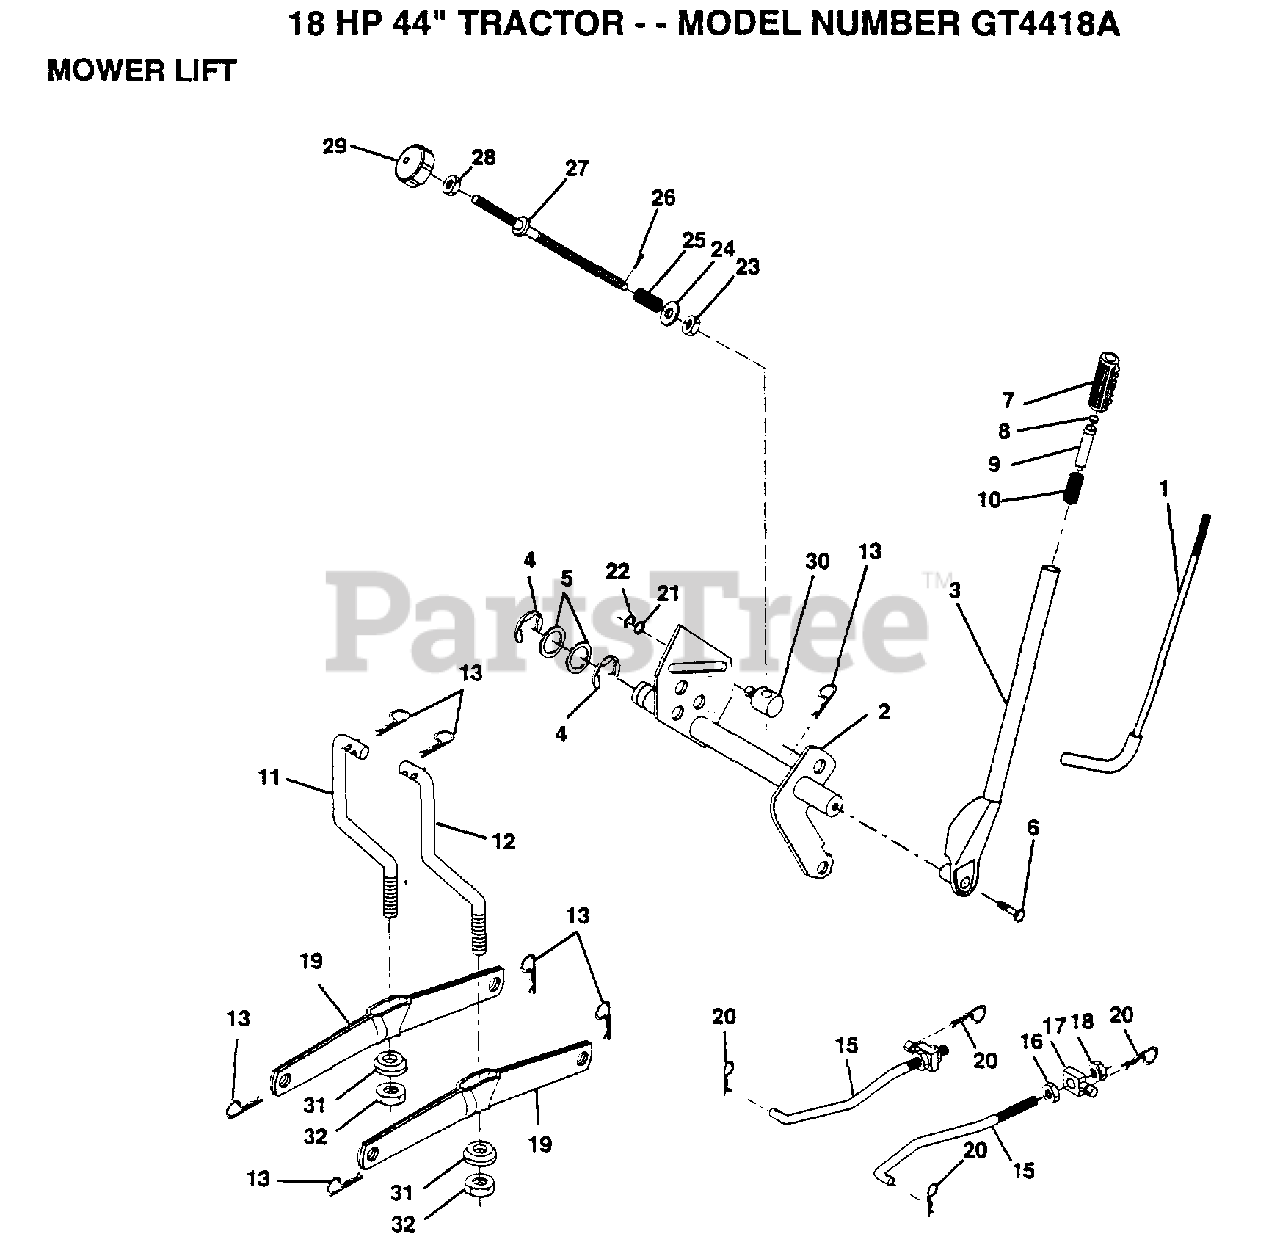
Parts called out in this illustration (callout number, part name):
1	LEVER ROD LT
2	SHAFT LIFT W/IND
4	E-RING
5	WASHER
6	"BOLT,HEX"
7	GRIP
10	SPRING T
11	LINK LIFT LH
12	LINK LIFT RH
15	LINK.FRONT
16	NUT
17	TRUNION
18	NUT.LK.W/WSH.1/2.
19	ARM SUSP REAR
20	RETAINER.SPRING
21	WASHER
22	KLIP RING
23	NUT T
24	WASHER
25	SPRING T
27	ROD LIFT LT
28	NUT
29	KNOB INF 3/8-16
30	TRUNION LT
31	BEARING PVT LH
32	NUT.LOCK.3/8-24
